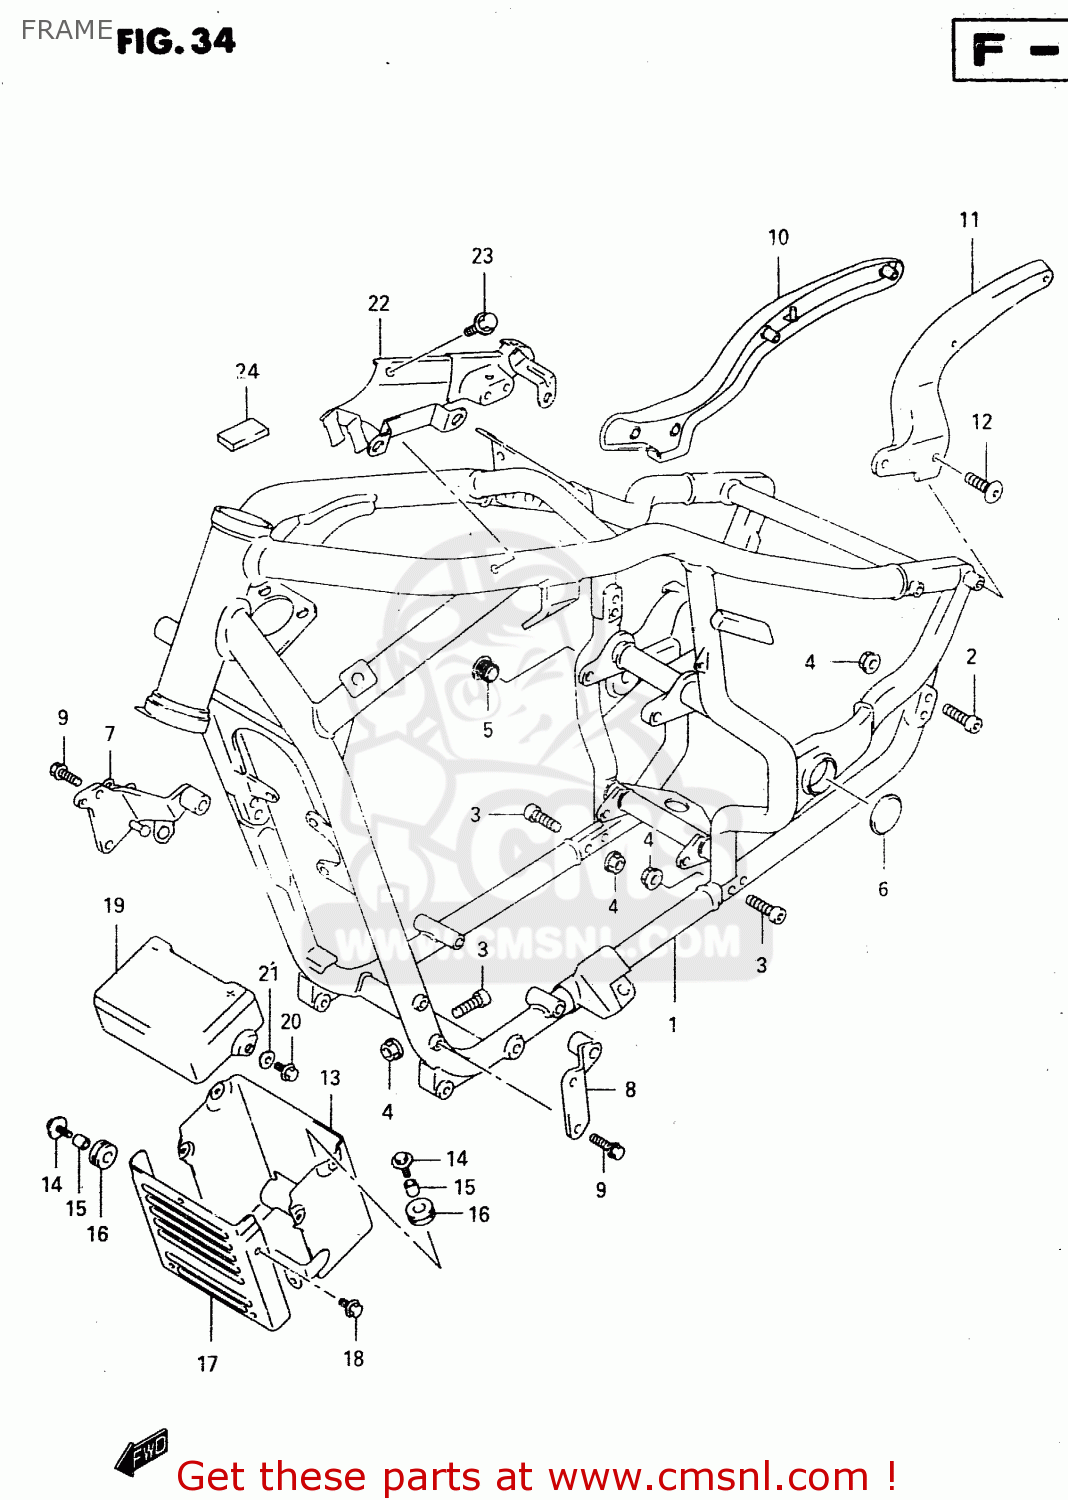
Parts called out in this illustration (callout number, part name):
1	FRAME COMP (BLACK)
2	BOLT
3	BOLT
4	NUT
5	CAP,FRAME U-LOCK HOLE
6	CAP,FRAME PIVOT,R
7	PLATE COMP,ENGINE MOUNTING
8	PLATE,ENGINE MOUNTING NO.1,LEFT
9	BOLT
10	GRIP COMP,FRAME HANDLE
11	GRIP COMP,FRAME HANDLE
12	BOLT,HANDLE GRIP
13	HOLDER COMP,BATTERY
14	BOLT(6X16)
15	SPACER(6.5X9X8)
16	CUSHION
17	HOLDER,BATTERY FR
18	SCREW
19	COVER,BATTERY,UPPER
20	BOLT
21	WASHER
22	PLATE COMP,ELECTRIC PARTS
23	BOLT
24	CUSHION
